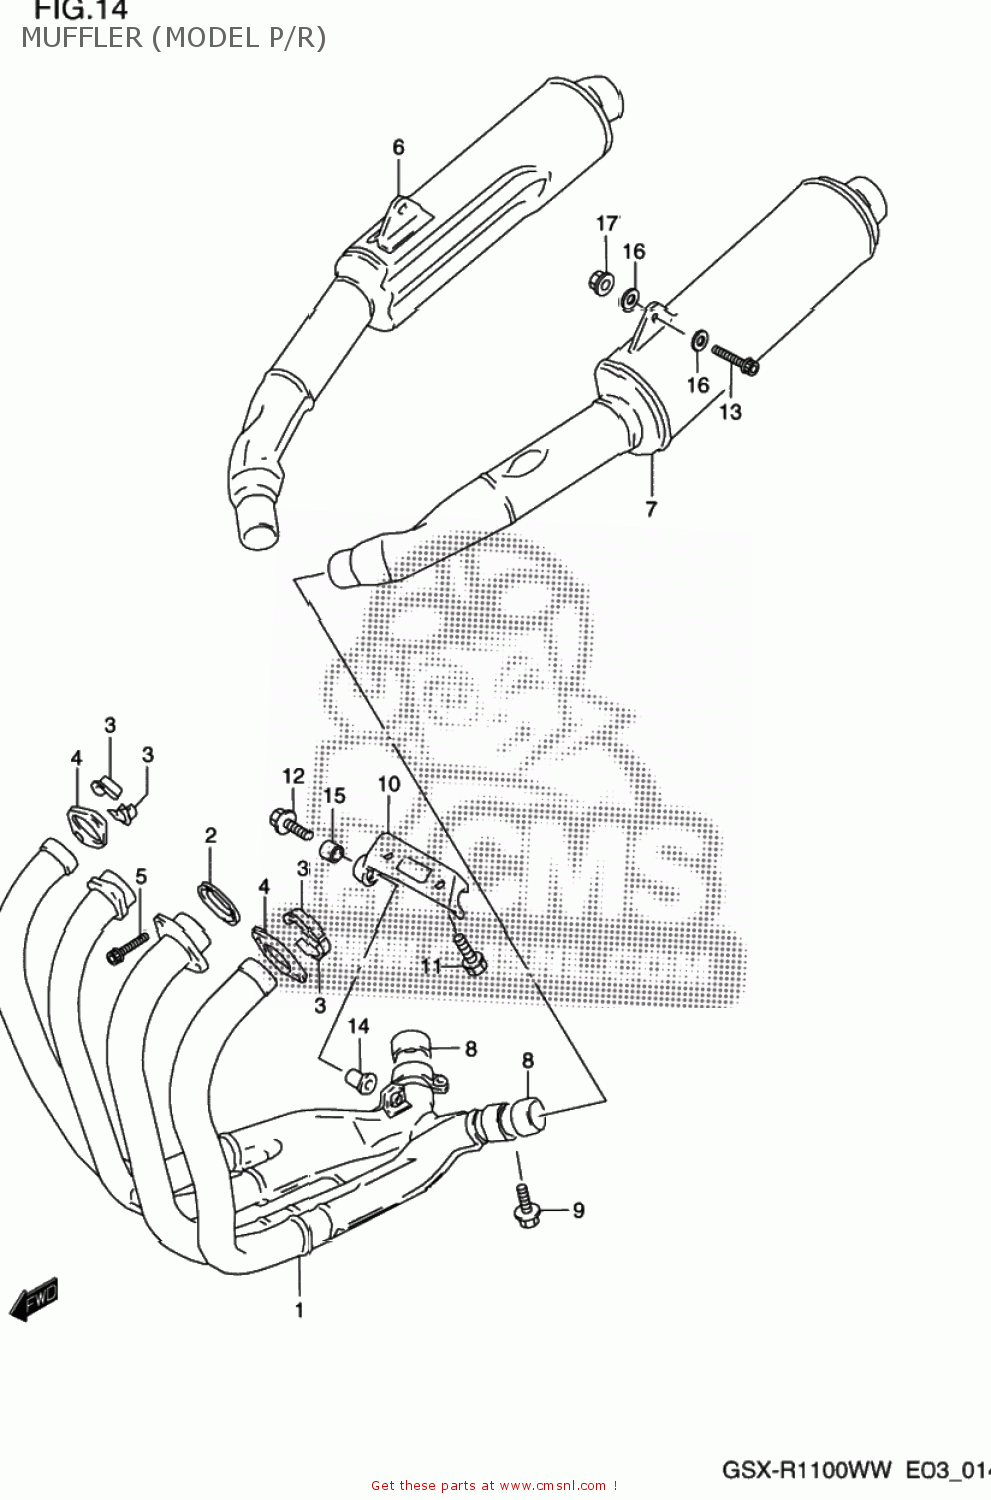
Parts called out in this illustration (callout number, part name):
1	EXHAUST ASSY
2	GASKET,EXHAUST PIPE
3	PLATE,EXHAUST PIPE
4	CLAMP,EXHAUST PIPE
5	BOLT
6	BODY,MUFFLER,RIGHT
7	BODY,MUFFLER,LEFT
8	CONNECTOR,MUFFLER
9	BOLT
10	DAMPER COMP,MUFFLER SUPPORT C
11	BOLT(8X20)
12	BOLT(8X35)
13	BOLT
14	SPACER(8.6X12X18.5)
15	CUSHION
16	WASHER (10.5X24X2.3)
17	NUT
